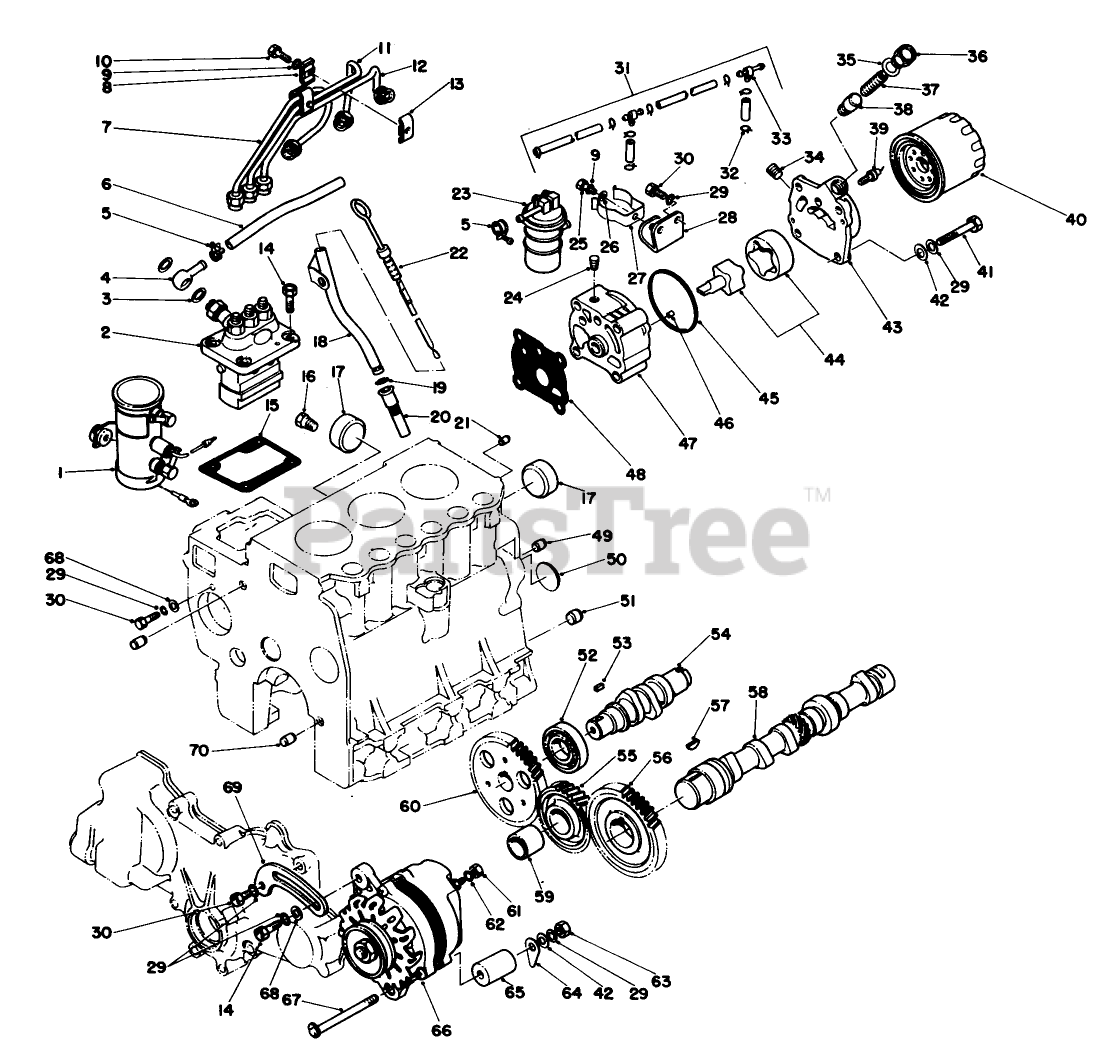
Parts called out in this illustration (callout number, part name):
1	Pump Assembly, Fuel Electric
2	INJ PUMP
3	SEAL WASHER
4	COLLAR MM 304916
5	CLAMP-HOSE
6	FUEL HOSE
7	1. PIPE ASM MM 409094
8	Clamp
9	WASHER-LOCK, SPRING
10	Screw
11	PIPE ASY.
12	3. PIPE ASM
13	Clamp
14	Screw-HH
15	ADJ SHIM MM 409040
16	PLUG-PIPE, SQH
17	SEALING CAP
18	Guide-Oil Level Gauge
19	O-RING
20	LEVEL RET
22	OIL GAGE
23	FUEL FILTER
24	1/8 PLUG MS 661120
25	SCREW - CAP
26	Washer, Plain (6)
27	FLTR CLAMP MM400880
28	FILTER SUPT MM409121
29	WASHER-LOCK, SPRING
30	BOLT
30	ADJ SCREW K 7231220
31	FUEL RETURN ASM
32	CLAMP-HOSE
33	JOINT MM 100088
34	Plug
35	GASKET
36	Plug
37	SPRING MM 407142
38	Plunger-Relief
39	OIL SWITCH
40	Filter-Oil
42	WASHER
43	PUMP COVER
44	PUMP ROTOR
45	O-RING
46	Pin-Dowe
47	PUMP BODY MM 409201
48	BODY GASKET MM 407124
49	KNOCK BSHG MS 471104
50	PLUG-40 MM MF665511
51	KNOCK BSHG MS 471110
52	Bearing Ball
53	SUNK KEY
54	(SHAFT) MM 408964
55	IDLER GEAR
56	Gear-Camshaft
57	5MMX19MM KEY
58	CAMSHAFT MM 408906
59	Bushing, Idler Gear
60	(GEAR) MM 406685
61	M5 HEX NUT
62	WASHER-LOCK, SPRING
63	NUT-HEX
65	SPACER
66	ALTERNATOR
67	BOLT MD 017625
68	WASHER
69	GEN BRACE MM 409463
70	KNOCK BSHG MS 471105
